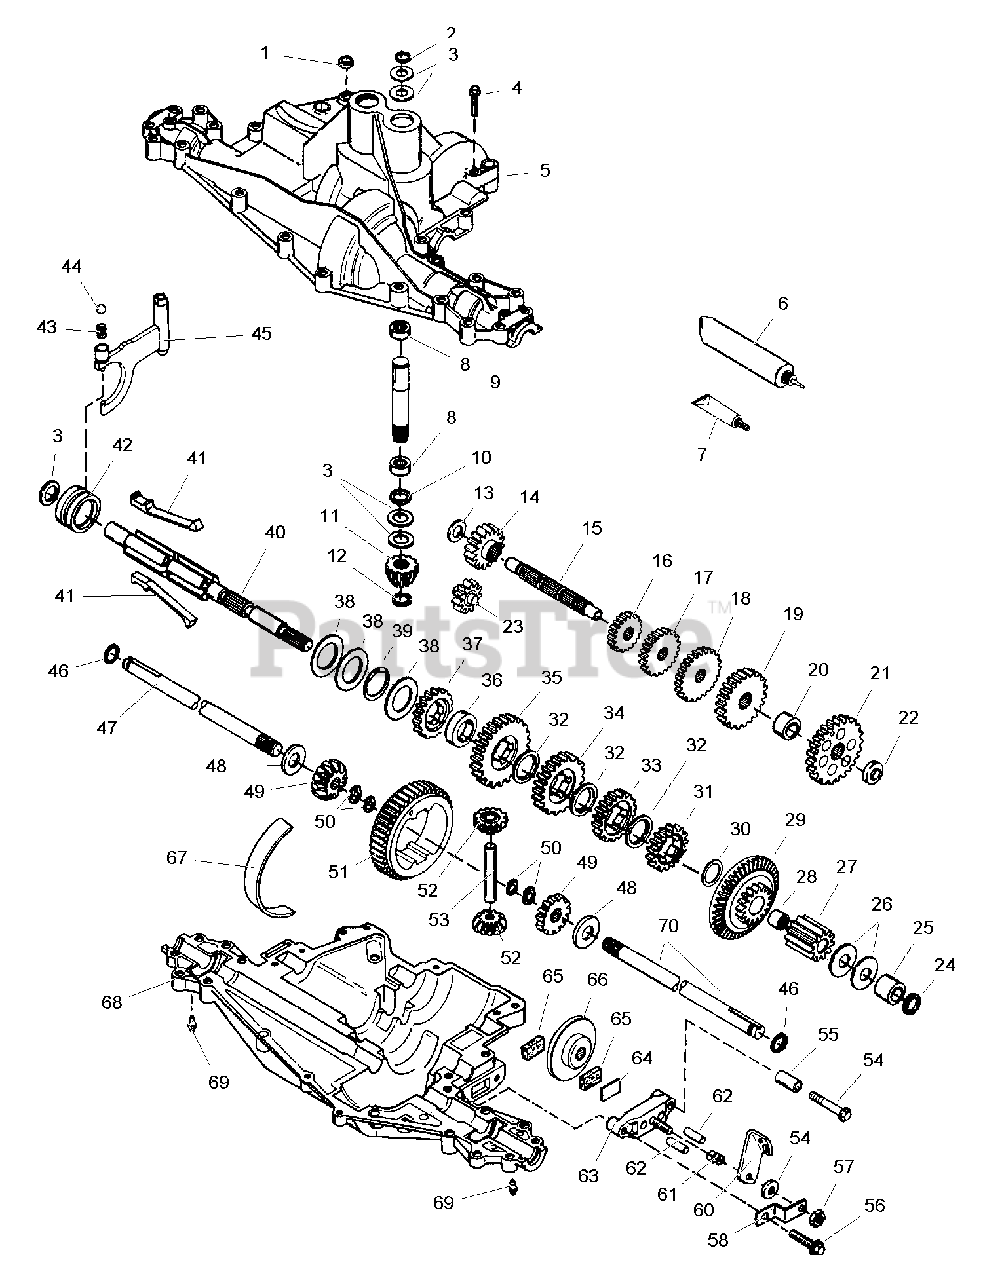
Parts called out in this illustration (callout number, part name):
1	* SEAL, Square Cut
2	* RING, Retaining
3	* WASHER, Thrust
4	* CAPSCREW, Hex Head Flange, Threadforming, 1/4-20 x 1-1/4
5	* COVER, Transaxle
6	* GREASE, 32 Oz. Bottle
7	* GASKET ELIMINATOR (Loctite #515)
8	* BEARING, Needle
9	* SHAFT, Input (3-5/16" Long)
10	* "O" RING
11	* BEVEL PINION, Input
12	* RING, Retaining
13	* WASHER, Thrust
14	* GEAR, Spur (16 Teeth)
15	* COUNTERSHAFT, (4-7/8" Long)
16	* GEAR, Spur (15 Teeth)
17	* GEAR, Spur (23 Teeth)
18	* GEAR, Spur (28 Teeth)
19	* GEAR, Spur (30 Teeth)
21	* GEAR, Spur (34 Teeth)
22	* WASHER, Thrust
23	* IDLER ASSEMBLY Reverse
24	* SEAL, Square Cut
25	* BUSHING
26	* WASHER, Thrust
27	* GEAR, Spur (11 Teeth)
28	* BEARING, Needle
29	GEAR
30	* WASHER, Thrust
31	* GEAR, Spur (19 Teeth)
32	* WASHER, Thrust
33	* GEAR, Spur (22 Teeth)
34	* GEAR, Spur (27 Teeth)
35	* GEAR, Spur (35 Teeth)
36	* SPACER, Neutral
37	* GEAR, Spur (22 Teeth)
39	* RING, Retaining, Inverted
40	* SHAFT, Brake (4 Keyed)
41	* SHIFT KEY
42	* COLLAR, Shifter
44	* BALL, Steel
45	* ROD & FORK ASSEMBLY, Shift
46	* SEAL RING
47	* AXLE, (16-13/16" Long)
49	* GEAR, Bevel, 13 Teeth (Includes Ref. No. 14)
50	* RING, Retaining, (Pkg. of 2)
51	* RING GEAR (43 Teeth)
52	* PINION, Bevel, (Includes Ref. No. 13)
53	* PIN, Drive
54	* CAPSCREW, Hex Head, Flange, Threadforming, 1/4-20 x 2-1/4
56	* CAPSCREW, Hex Head, Flange, Threadforming,1/4-20 x 1-1/4
57	* NUT, Lock, 5/16-24
58	* BRACKET, Brake Lever
59	* WASHER, Flat
60	* LEVER, Brake
61	* SPRING, Brake
62	* PIN, Dowel
63	* HOLDER, Brake Pad
64	* PLATE, Brake Pad
65	* PAD, Brake (Pkg. of 2)
66	* DISK, Brake
67	* STRIP, Bearing
68	* CASE, Transaxle
69	* FITTING, Lubrication
70	* AXLE, (11-5/8" Long) (Includes Ref. No. 26, Qty. 2)
